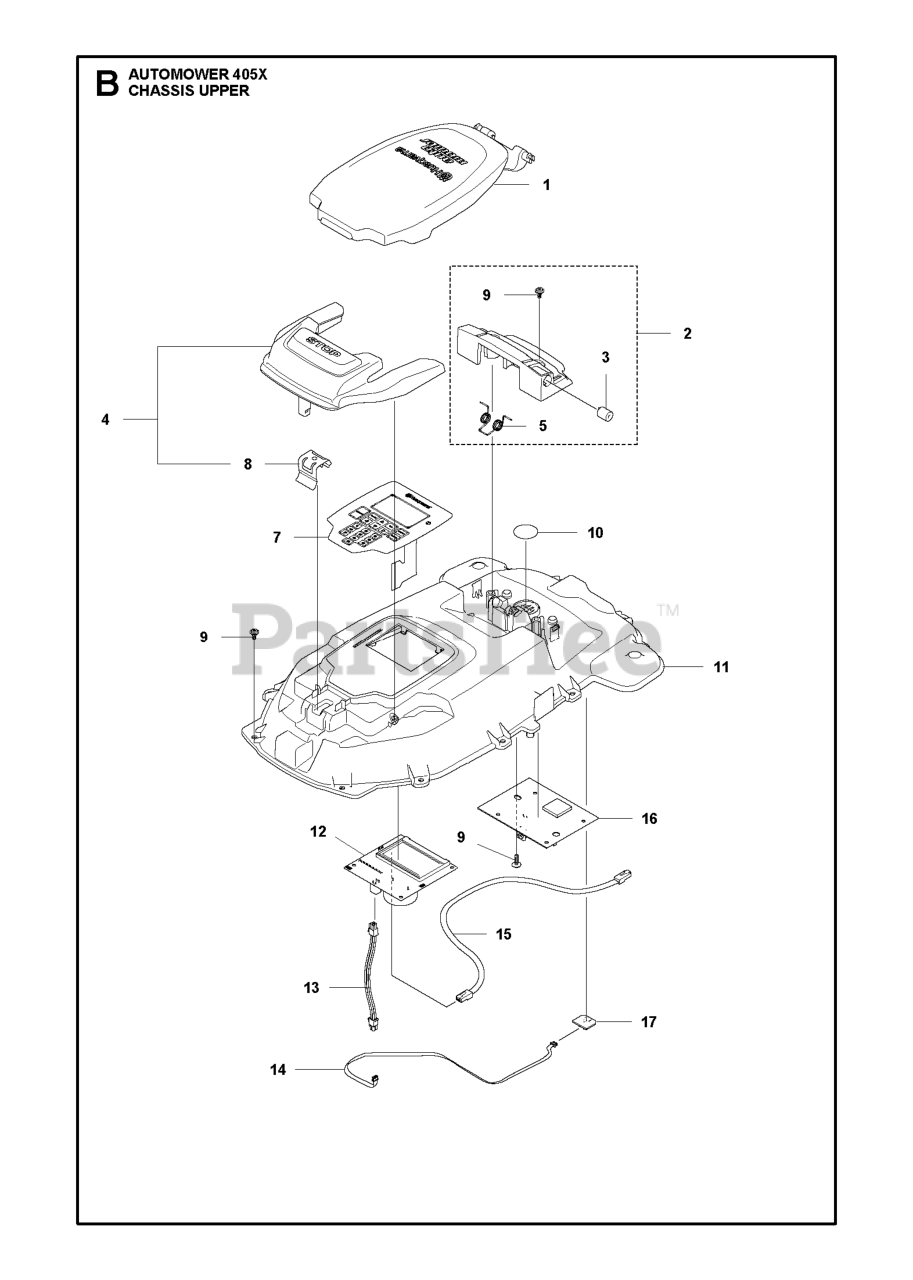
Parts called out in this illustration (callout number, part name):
2	SUPPORT FRONT ASSY
3	DAMPER TORSION FA 1100
4	BUTTON KIT STOP BUTTON AM405X/
5	TORSION SPRING DT=1,3MM
7	KEYBOARD P16
8	SPRING BUTTON STOP DELTA SEAL
9	SCREW ITXPANT
10	KIT AIR FILTER KIT 305 - 10 PC
11	CHASSIS UPPER - P16
12	PRINTED CIRCUIT ASSY PCBA APPL
13	Wires
14	WIRING ASSY MAGNETIC SENSOR WI
15	WIRING ASSY MODULAR JACK 6/6 R
16	GPS MODULE 2G + 3G
17	PRINTED CIRCUIT ASSY PCBA MAGN
